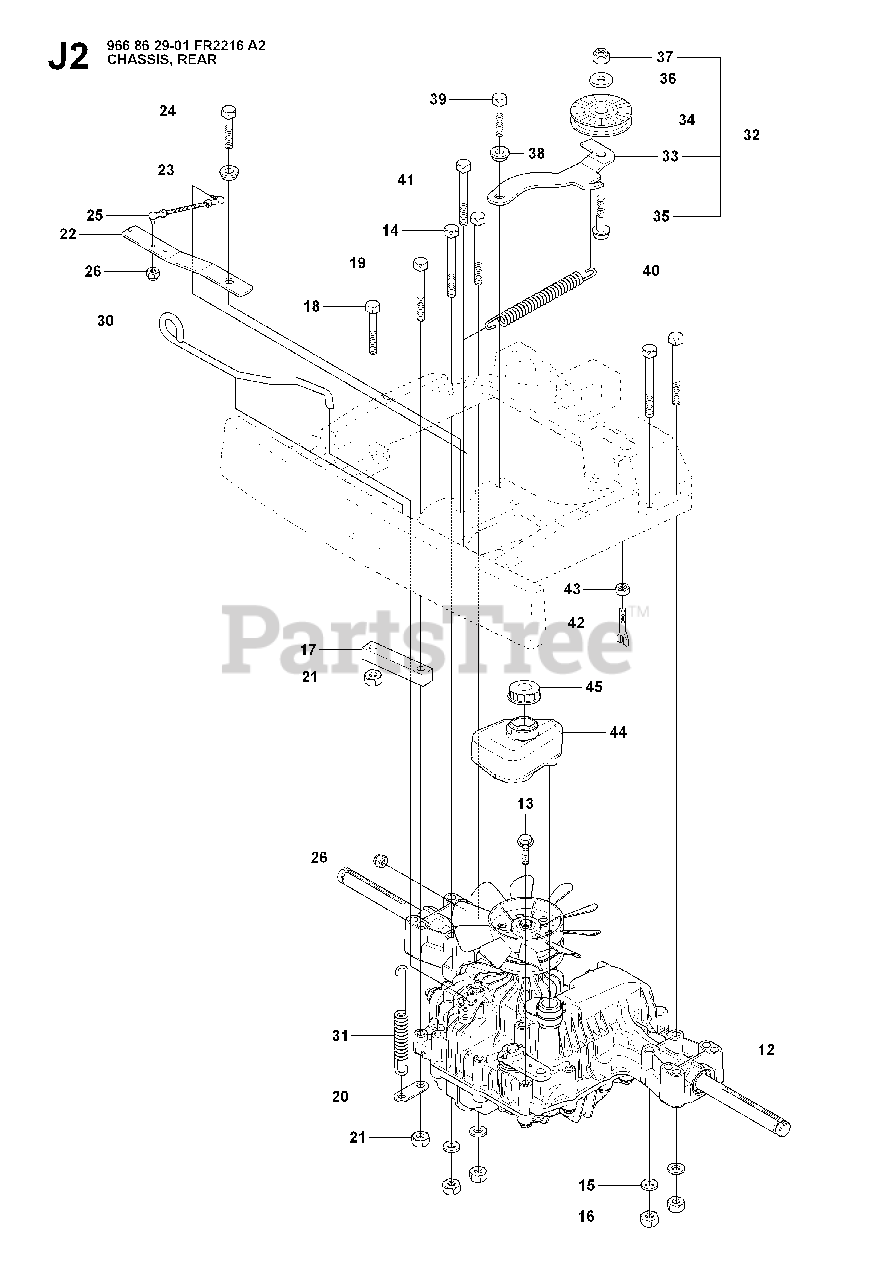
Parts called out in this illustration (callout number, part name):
2	BALL BEARING 6005-2RS
3	BALL BEARING 6010 2RS1
4	CIRCLIP SGH 47
5	RETAINING RING SGA 25
7	RETAINING RING SGA 25
12	HYDROSTAT
15	WASHER BRB 8.4X17
16	NUT
20	CONNECTOR
21	NUT
23	WASHER
24	SCREW 8X20
26	LOCKNUT M5
31	SPRING
32	TENSIONER
33	TENSIONER
37	LOCKNUT M8
38	WASHER
39	SCREW 8X20
46	DRAW RING
